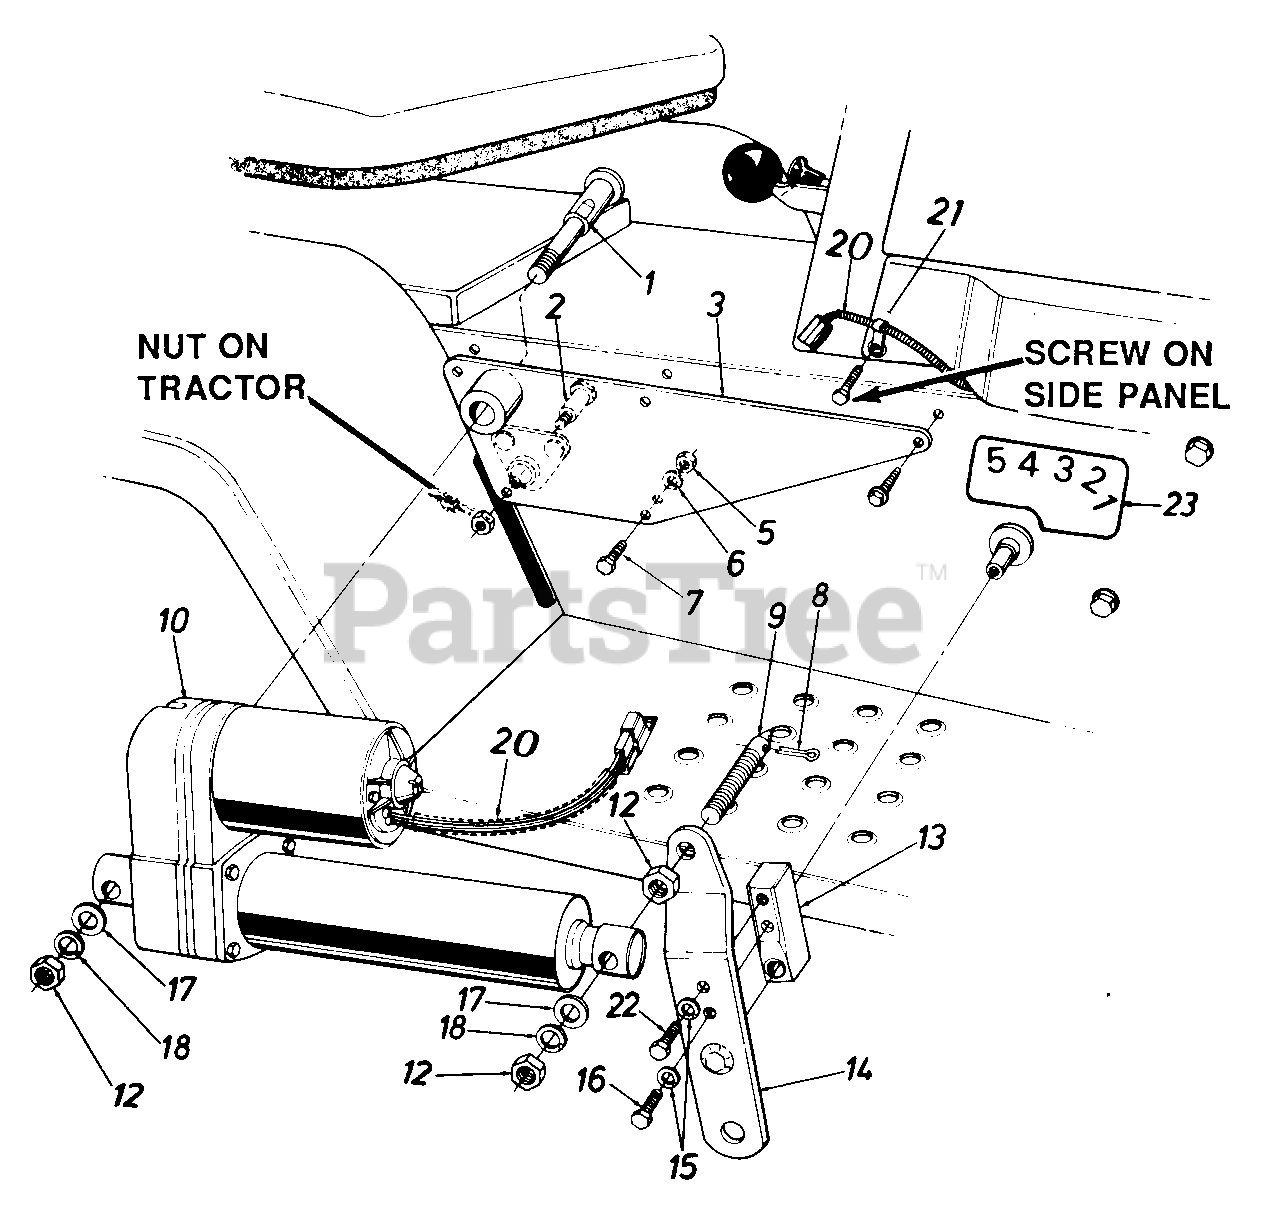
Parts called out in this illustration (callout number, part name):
1	Pivot Pin
2	Shld. Bolt.626 Dia. x .96"
5	Hex Nut 1/4-28 Thd.
6	L-Wash. 1/4" I.D.
7	Hex Bolt 1/4-28 x .75" Lg. (Grade 5)
8	Cotter Pin
9	Indicator& Mtg. Pin
10	Electric Actuator
12	Hex Jam Nut 1/2-13 Thd.
13	Lift Shaft Drive
16	Hex Bolt 5/16-24 x 1.0" Lg. (Grade 5)
17	Fl-Wash. .53" I.D. x .93"O.D.
18	L-Wash. 1/2" I.D.
20	Plastic Harness
21	Clamp
22	Hex Bolt 5/16-18 x 1" Lg. (Grade 5)
23	Label
